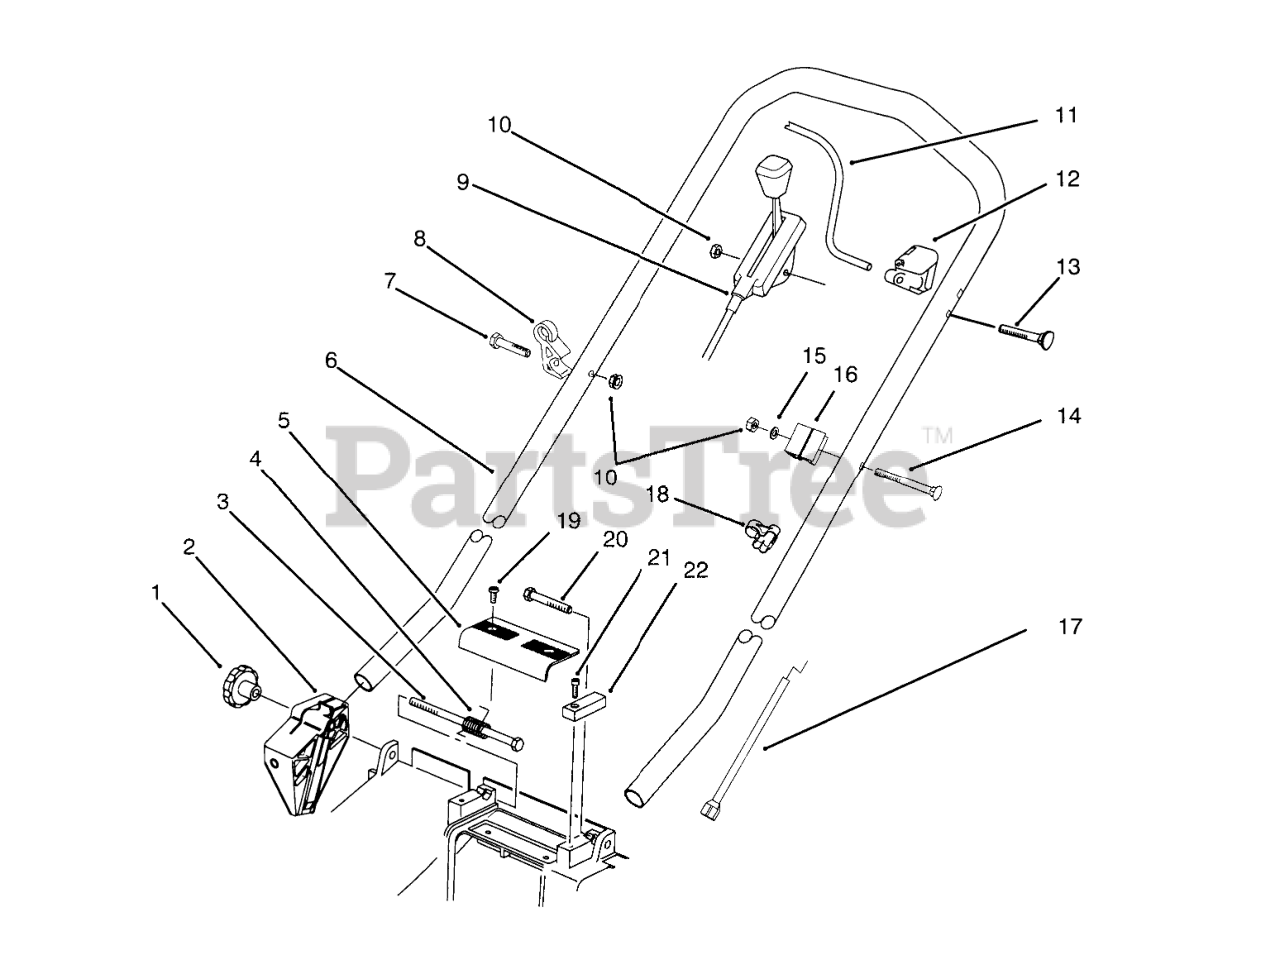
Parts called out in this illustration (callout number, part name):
2	Mount-Handle R.H.
3	BOLT-LONG
4	SPRING-DOOR
5	GRIP-UPPER
6	HANDLE
7	.250-20X1.625 HH SCREW
8	GUIDE - ROPE
9	CONTROL - THROTTLE
10	NUT-LOCK, NI
11	BAIL - CONTROL
12	Stop-Pivot
13	SCREW-HANDLE
14	SCREW-HANDLE
15	WASHER-FLAT
16	SUPPORT-CABLE
17	CABLE - BRAKE
18	CLAMP-CABLE
19	SCREW-PPH, PLASTITE
20	BOLT-SHORT
21	SCREW-CAP, HINGE
22	CAP-BOLT
